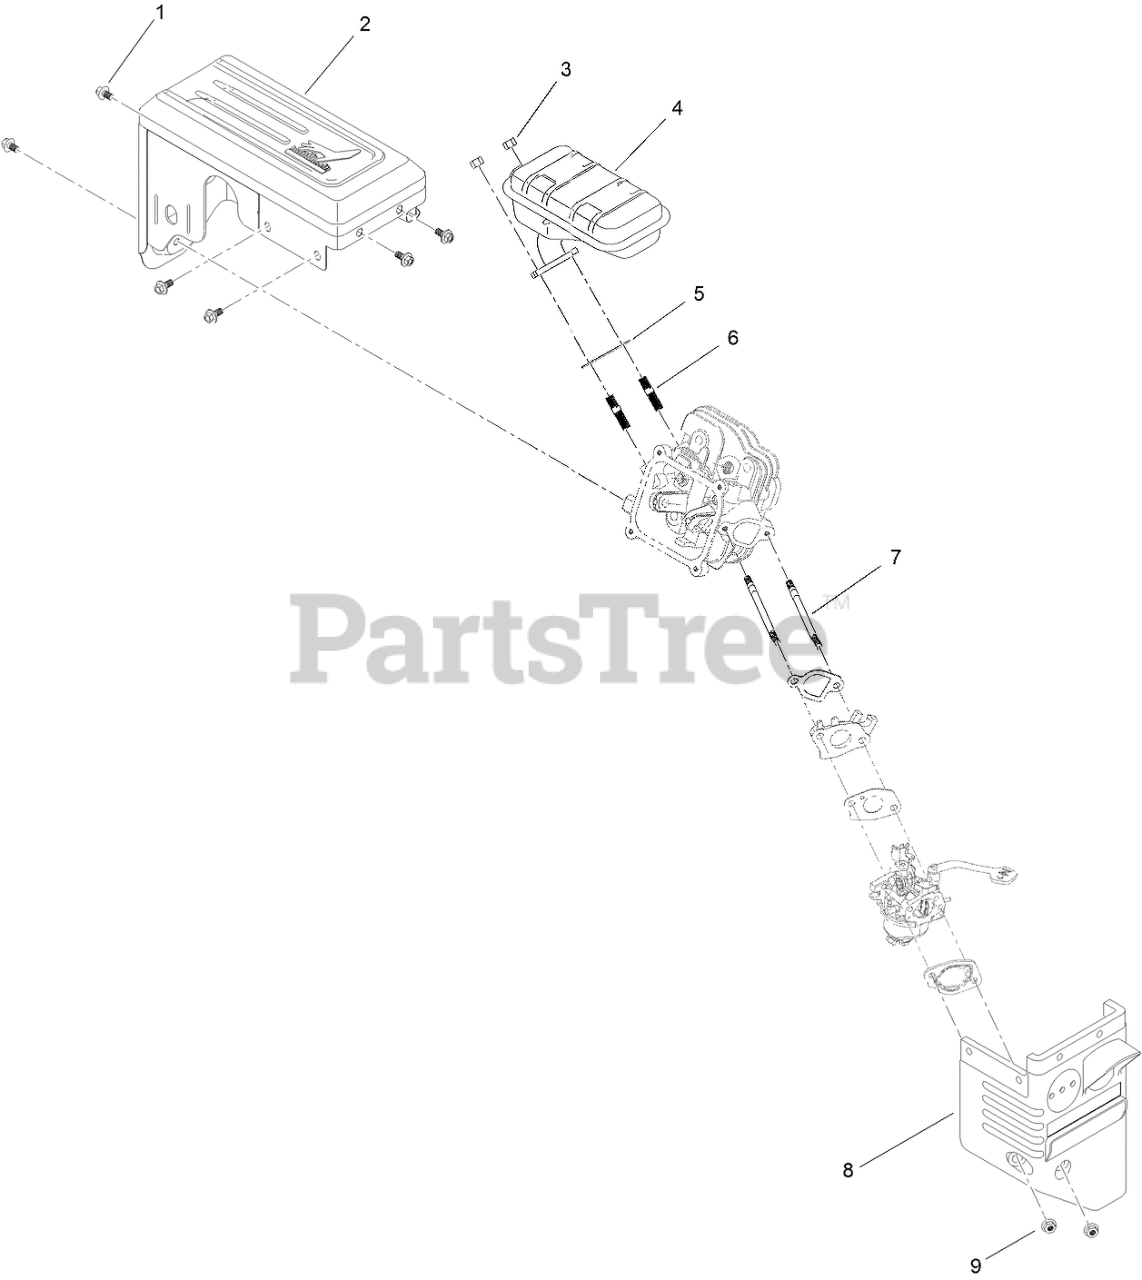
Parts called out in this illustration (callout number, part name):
1	SCREW-HHF
2	MUFFLER SHROUD ASM
3	NUT-HH
4	MUFFLER ASM
5	GASKET-EXHAUST
6	STUD-EXHAUST
7	STUD-INTAKE
8	BOX-HEATER
9	NUT-FLANGE
